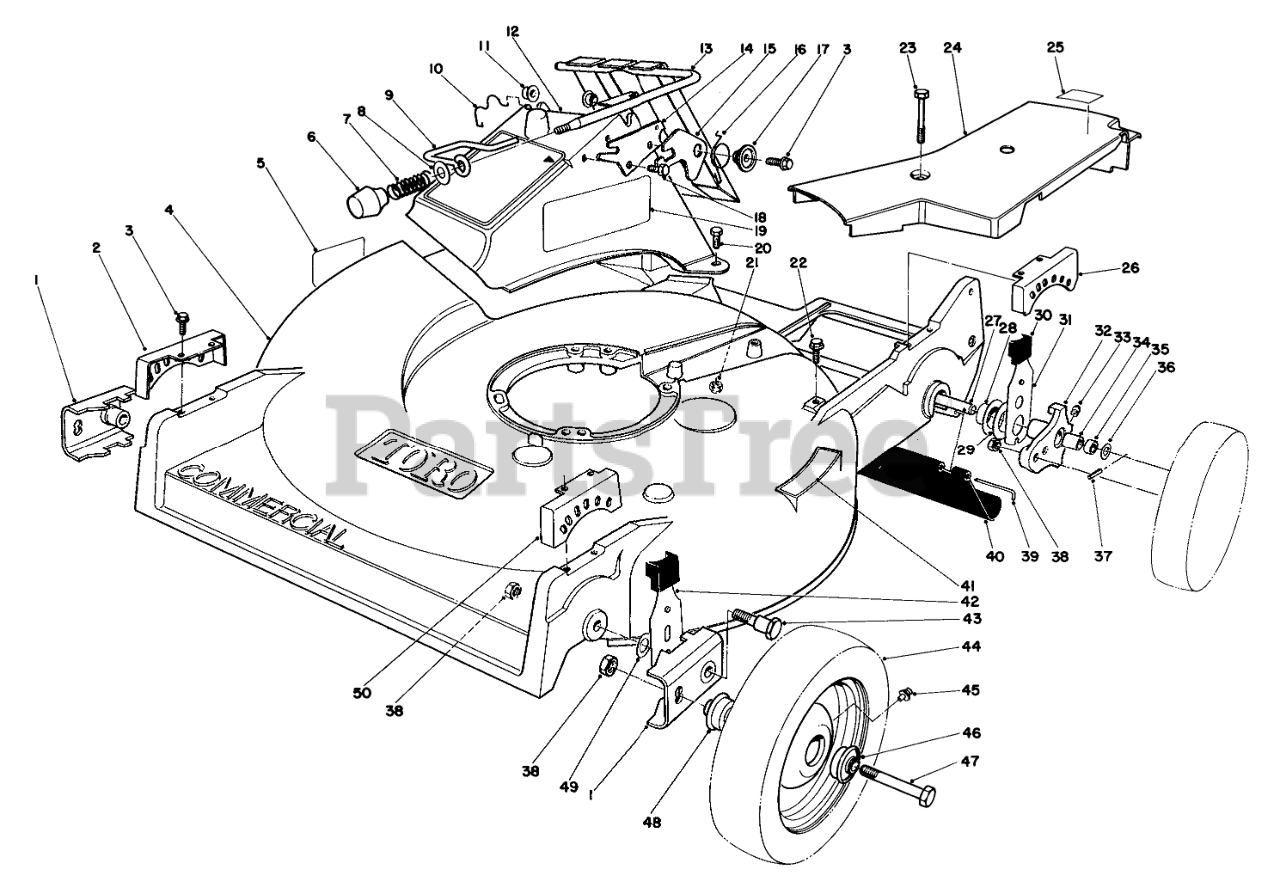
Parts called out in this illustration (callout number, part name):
1	PIVOT ARM
2	QUADRANT-FRONT, RH
3	Screw
4	Housing
5	DECAL-DANGER
7	COMPRESSION SPRING
8	WASHER-FLAT
9	DOOR LATCH
10	DOOR RETAINER
11	BUSHING-NYLON
12	Chute & Door Assembly (Incl. Ref. #3 & 6-21)
13	DOOR & HANDLE WA
14	DOOR LATCH PLATE
15	SAFETY LATCH
16	TORSION SPRING
17	DOOR SPACER
18	SCREW-HWH
19	DECAL SAF INST
20	SCREW-HH
21	NUT-LOCK, NI
22	SCREW-HWHTF
23	SCREW-HHFTF
24	Belt-Cover
25	Label-Grease
26	QUADRANT-REAR, LH
27	SHAFT-AXLE, REAR
28	CAP-END
29	WASHER
30	KNOB-ARM
31	Spring Arm
32	Pivot Arm (Incl. Ref. #33-35)
33	FITTING-GREASE
34	BUSHING
35	BUSHING
36	WASHER-PLAIN
37	PIN-SPIROL
38	NUT-LOCK, NI
39	ROD-SHIELD
40	SHIELD-TRAILING
41	STEP PAD DECAL
42	SPRING ARM ASM-FRONT
43	PIVOT SCREW
44	Wheel & Tire Assembly (Incl. Ref. #45, 46 & 48)
45	FITTING-GREASE
46	WHEEL BRG
47	SCREW-HH
48	WHEEL BEARING
49	WASHER-PIVOT
50	QUADRANT-FRONT, LH
